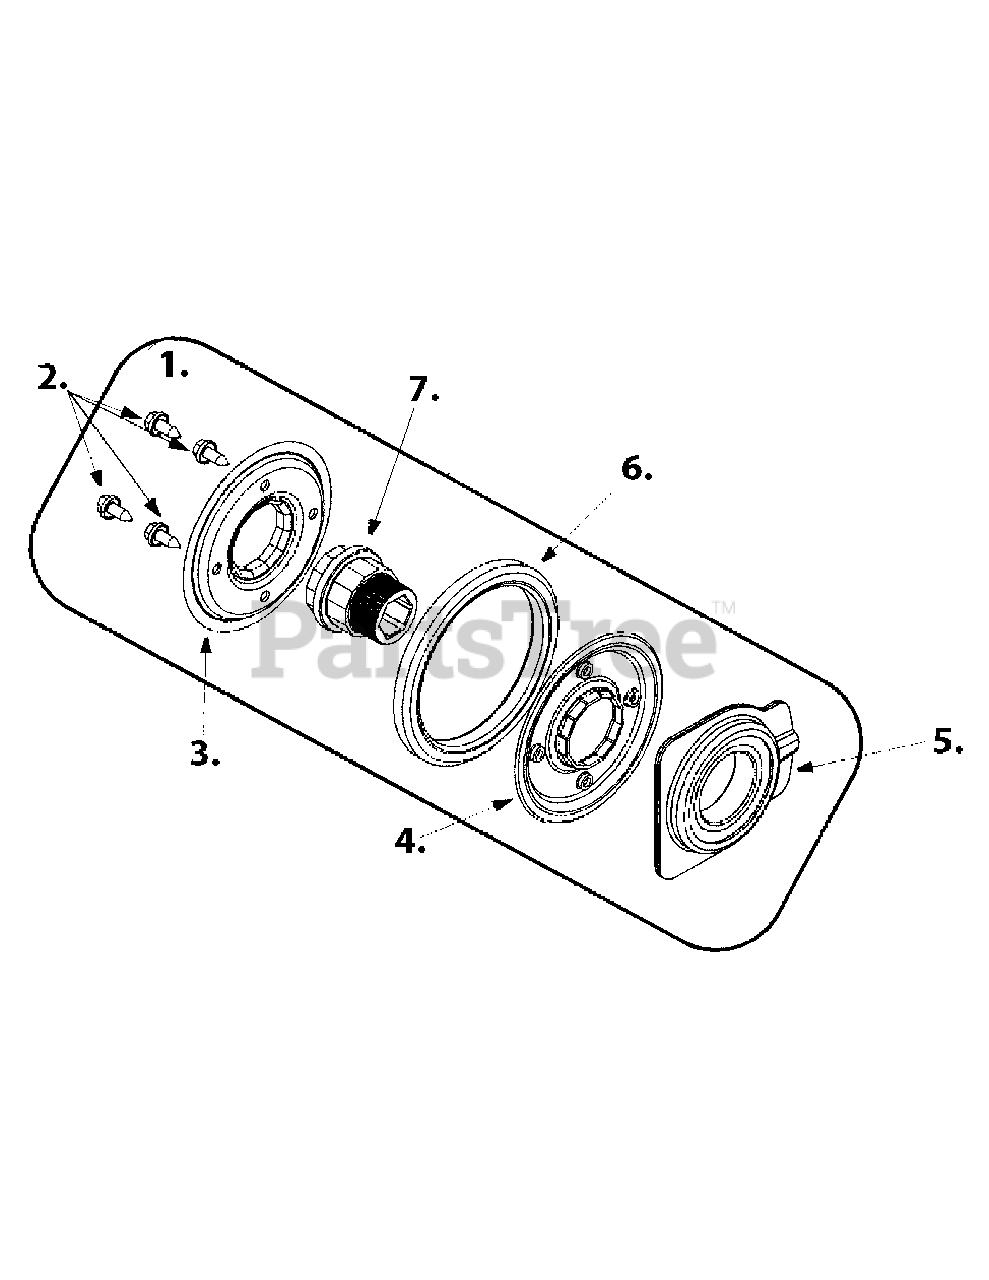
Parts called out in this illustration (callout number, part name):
1	Friction Wheel Assembly
2	AB Screw 1/4-14 x.625
3	Friction Plate
4	Friction Plate
5	Friction Wheel Bearing
6	Friction Wheel Rubber
7	Friction Wheel Hub
